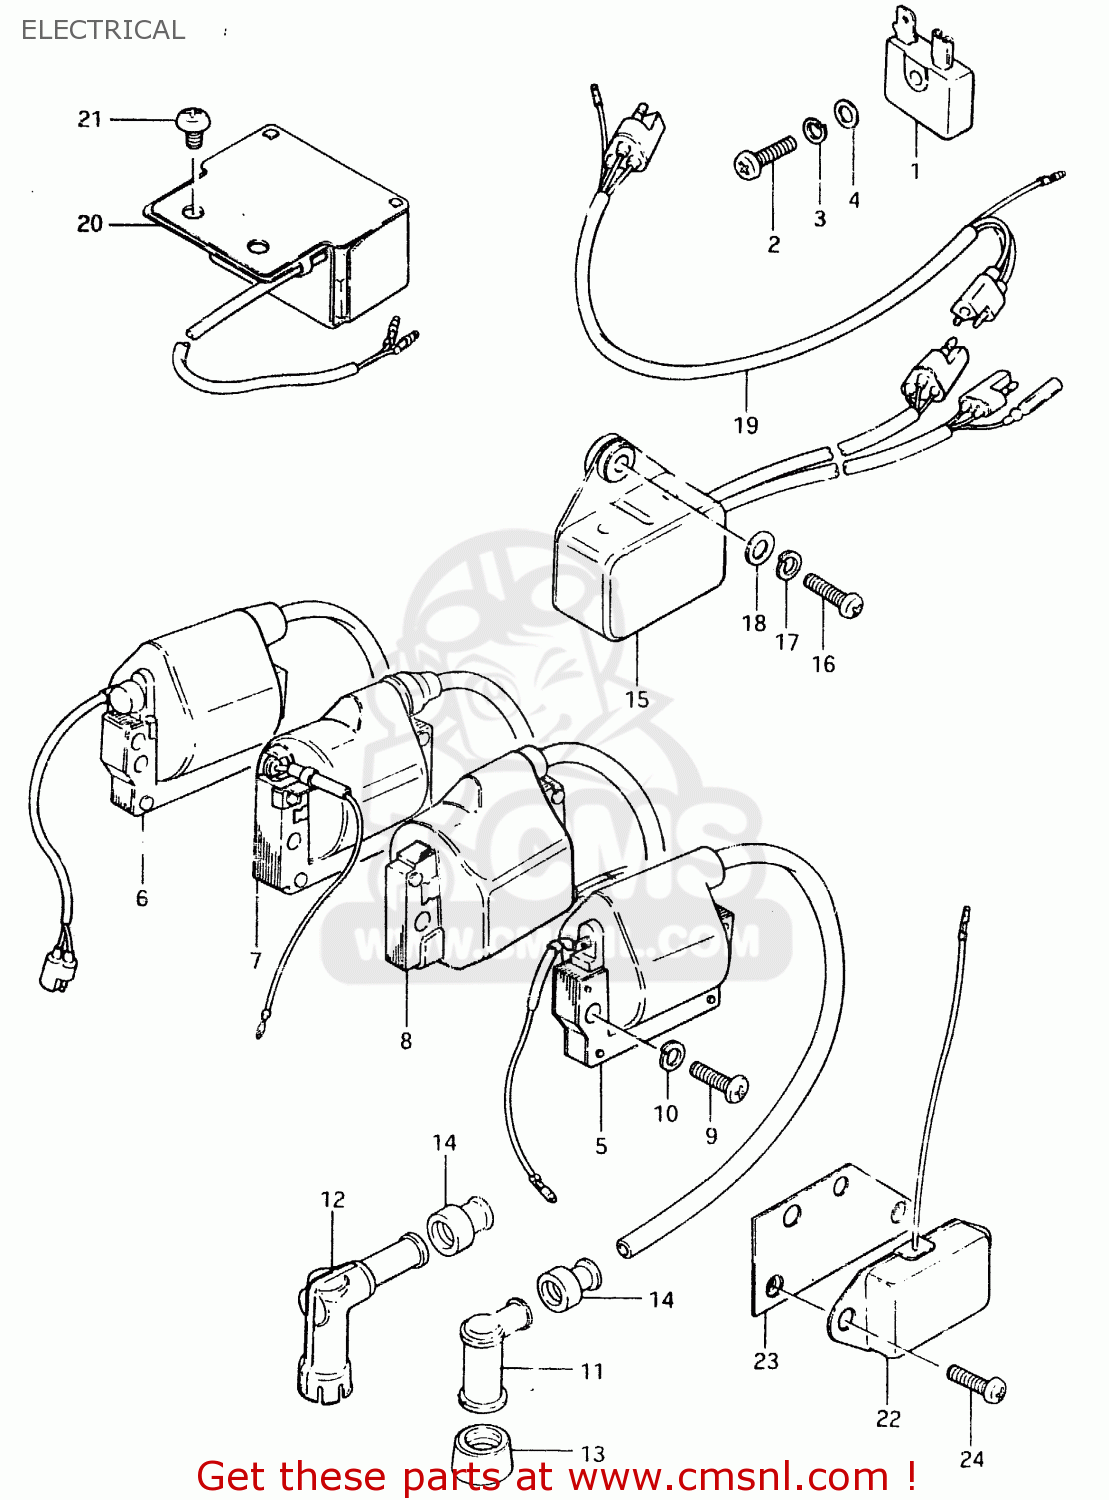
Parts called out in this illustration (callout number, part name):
1	RECTIFIER ASSEMBLY
2	SCREW 5X20
3	LOCK WASHER
4	WASHER
5	COIL ASSEMBLY,IGNITION
6	COIL ASSY, IGNITION
7	COIL ASSEMBLY,IGNITION
8	UNIT & COIL ASSEMBLY,IGNITION
9	SCREW
10	LOCK WASHER
11	CAP ASSY,SPARK PLUG
12	CAP,SPARK PLUG
13	SEAL,SPARK PLUG
14	SEAL,SPARK PLU
15	CDI UNIT
16	SCREW
17	LOCK WASHER
18	WASHER
19	LEAD WIRE, CDI
20	RESISTOR ASSY
21	SCREW
22	REGULATOR ASSEMBLY,VOLTAGE
23	PLATE
24	SCREW
